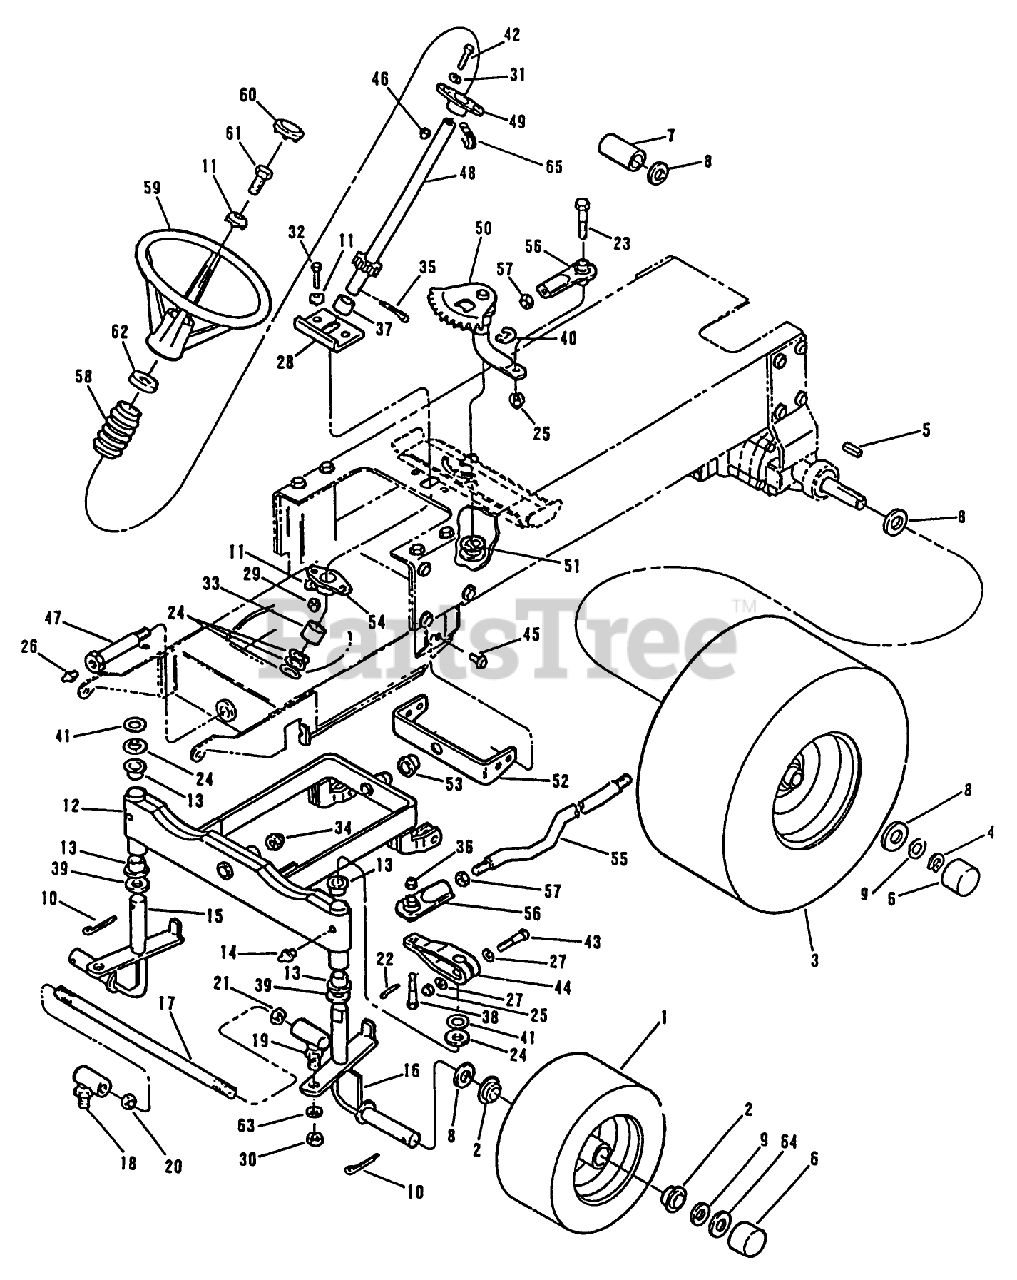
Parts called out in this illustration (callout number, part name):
7	SPACER-WHEEL
12	AXLE AY-FRONT
13	BEARING - BRONZE
16	SPINDLE ASM - LH
18	BALL JOINT, RH
19	BALL JOINT-LH
21	NUT HEX JAMB LH
25	NUT-LOCKING
30	HEX NUT
34	NUT-HEX
39	WASHER - THRUST
41	WASHER - SPECIAL
42	SCREW-HH
46	NUT-LOCK, CONE
49	BEARING AY.
56	BALL JOINT
57	NUT-HEX
61	SCREW - HEX
65	CLAMP - J EX
